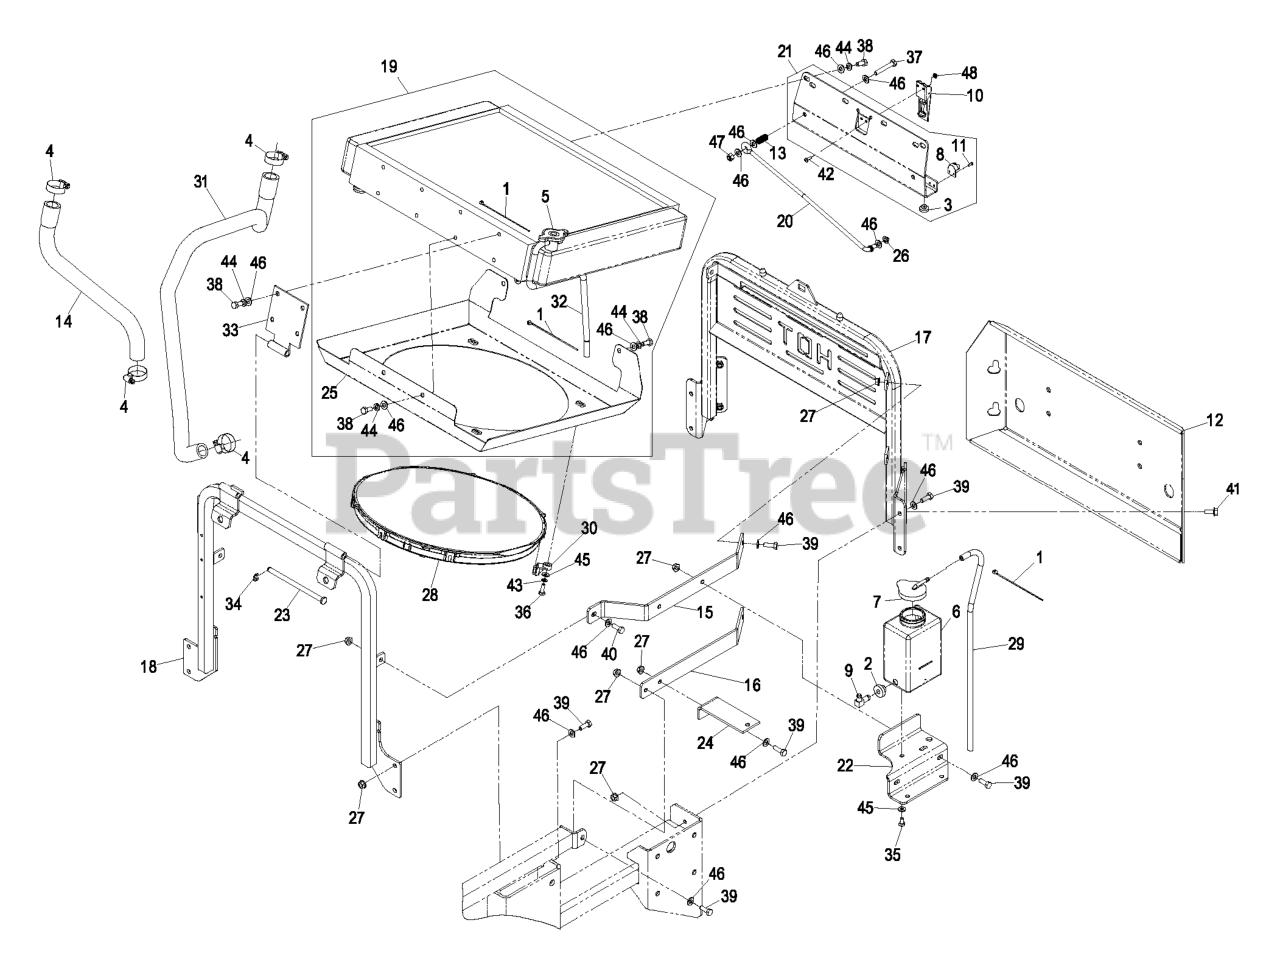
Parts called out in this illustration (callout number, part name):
1	TIE-CABLE
5	CAP-RADIATOR
6	TANK-OVERFLOW
7	CAP-TANK, OVERFLOW
10	LATCH-CAMLOC
12	WLD,REAR BUMPER
13	SPRING,LOCK PIN
14	HOSE,RADIATOR UPPER D902(
16	RIB, BOTTOM
18	ASM, RAD. MOUNT W/ DECALS
20	ROD,PROP
21	ASM,LATCH PLATE W/DECALS
22	BRACKET,BOTTLE
24	BRACKET, HYDRAULIC TANK
25	SHROUD,FAN
30	MOUNT,FAN
31	HOSE,RADIATOR LOWER D902
32	HOSE,OVERFLOW
33	WLD,HINGE PLATE
35	SCREW-HH
36	SCREW-HH
37	SCREW-HH
38	SCREW-HH
39	SCREW-HH
40	SCREW-HH
41	SCREW-HHF
42	SCREW-PPH
43	SCREW-HH
44	WASHER-LOCK
45	WASHER-FLAT
46	WASHER-PLAIN
47	NUT-LOCK, NI
48	NUT-LOCK
